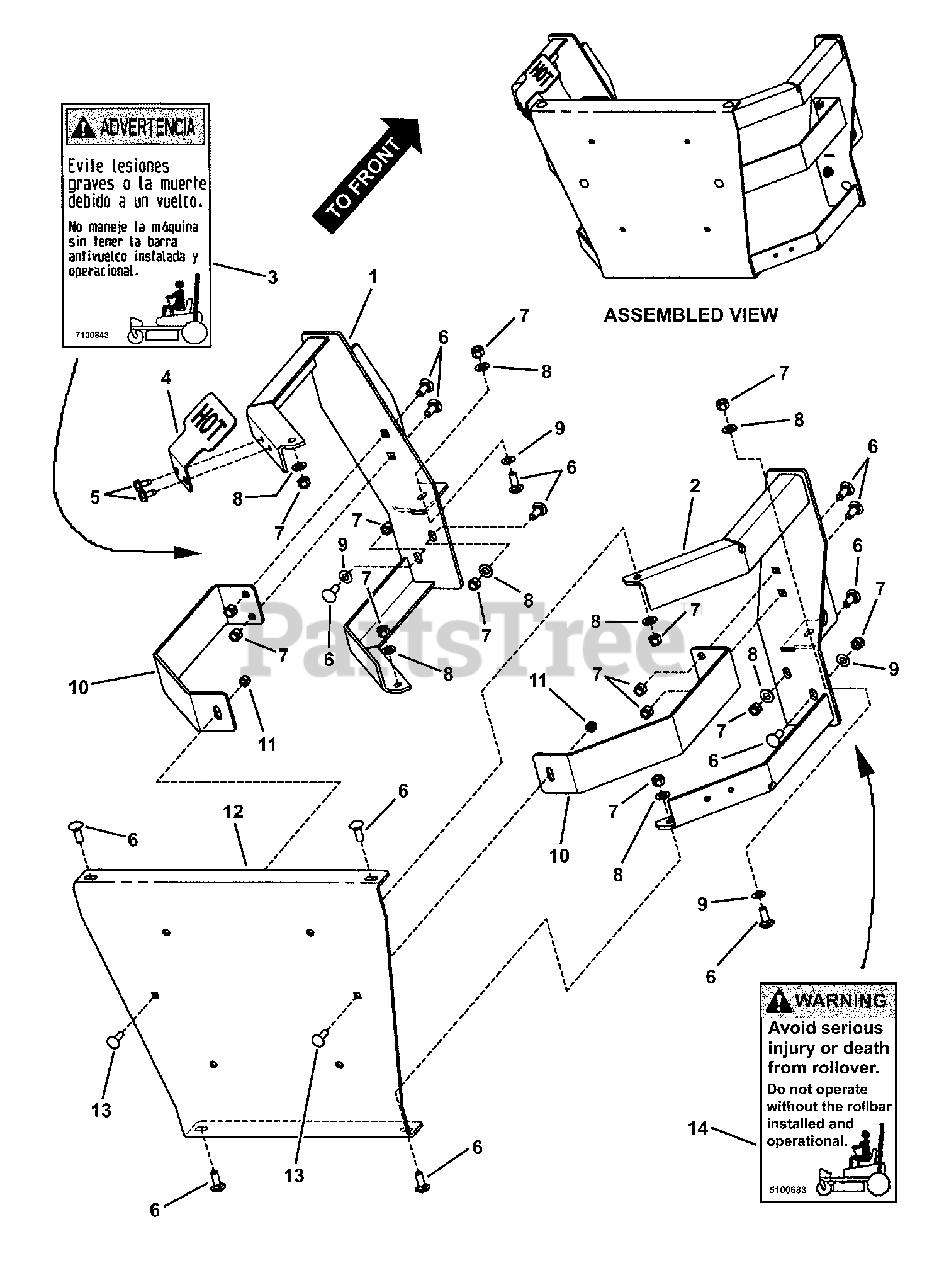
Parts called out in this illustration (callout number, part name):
1	WELDMENT, Bumper LH
2	WELDMENT, Bumper
3	DECAL, Warning, Rollbar (Spanish)
4	GUARD, Hot Plate
5	SCREW, 5/16-18 x 5/8" Hex Washer Self-Tap
6	BOLT, 3/8-16 x 1" Square Neck Carriage GR 5
7	NUT, 3/8-16 HEX NYLON LOCK
8	WASHER, 3/8" Flat SAE
9	BOLT RETAINER, 3/8"
10	BRACKET, Bumper Support, Middle
11	NUT, 5/16-18 HEX NYLON LOCK
12	BRACKET, Rear Bumper
13	BOLT, 5/16-18 x 1" Short Neck Carriage, GR 5
14	DECAL, Warning, Rollbar
